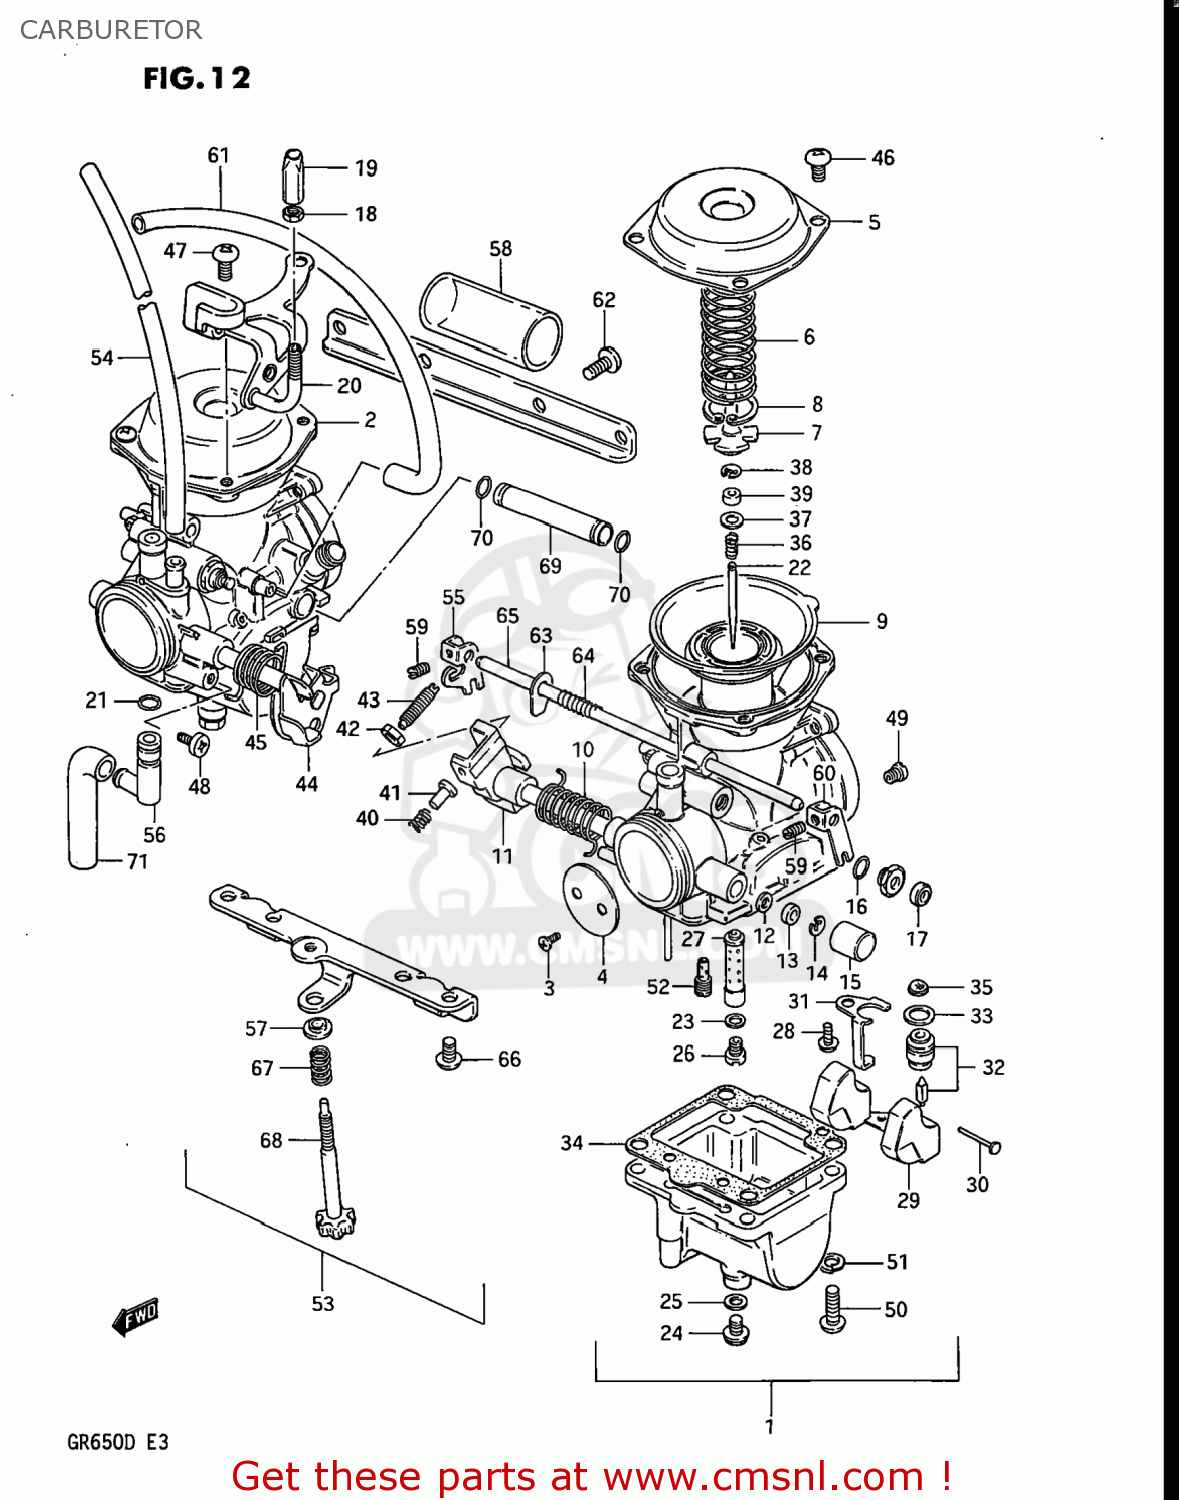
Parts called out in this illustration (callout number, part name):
1	CARBURETOR ASSEMBLY
2	CARBURETOR ASSEMBLY
3	SCREW
4	VALVE,THROTTLE (90)
5	COVER,DIAPHRAGM
6	SPRING,DIAPHRAGM
7	HOLDER,GUIDE
8	E RING
9	DIAPHRAGM,CARBURETOR
10	SPRING
11	SHAFT ASSEMBLY
12	SEAL
13	GASKET,THROTTLE SHAFT (NAS)
14	E RING
15	CAP
16	O RING
17	CAP,STARTER VALVE
18	NUT
19	ADJUSTER
20	BRACKET
21	O-RING
22	NEEDLE JET
23	WASHER,NEEDLE NOZZLE
24	PLUG,DRAIN
25	GASKET (NAS)
26	JET,MAIN(132.5)
27	JET,NEEDLE
28	SCREW 4X6
29	FLOAT
30	PIN,FLOAT
31	PLATE,NEEDLE VALVE FITING
32	VALVE ASSEMBLY,NEEDLE
33	O-RING,NEEDLE VALVE
34	GASKET,FLOAT CHAMBER (NAS)
35	FILTER
36	SPRING
37	WASHER
38	CLIP,NEEDLE
39	RING
40	SPRING,THROTTLE SCREW
41	PIN,THROTTLE LEVER
42	NUT
43	SCREW
44	SHAFT ASSEMBLY
45	SPRING
46	SCREW
47	SCREW
48	SCREW
49	JET
50	SCREW
51	LOCK WASHER
52	JET,PILOT(42.5)
53	CARBURETOR ASSEMBLY
54	HOSE
55	LEVER,STARTER
56	PIPE
57	RING,ADJUSTER
58	HOSE
59	SCREW,THROTTLE ADJUST
60	LEVER
61	HOSE
62	SCREW
63	WASHER,STARTER PLUNGER
64	SPRING,STARTER
65	SHAFT,STARTER
66	SCREW 6X12
67	THROTTLE SCREW
68	SCREW,THROTTLE STOP
69	PIPE,CARBURETOR
70	O RING
71	HOSE,CARBURETOR
